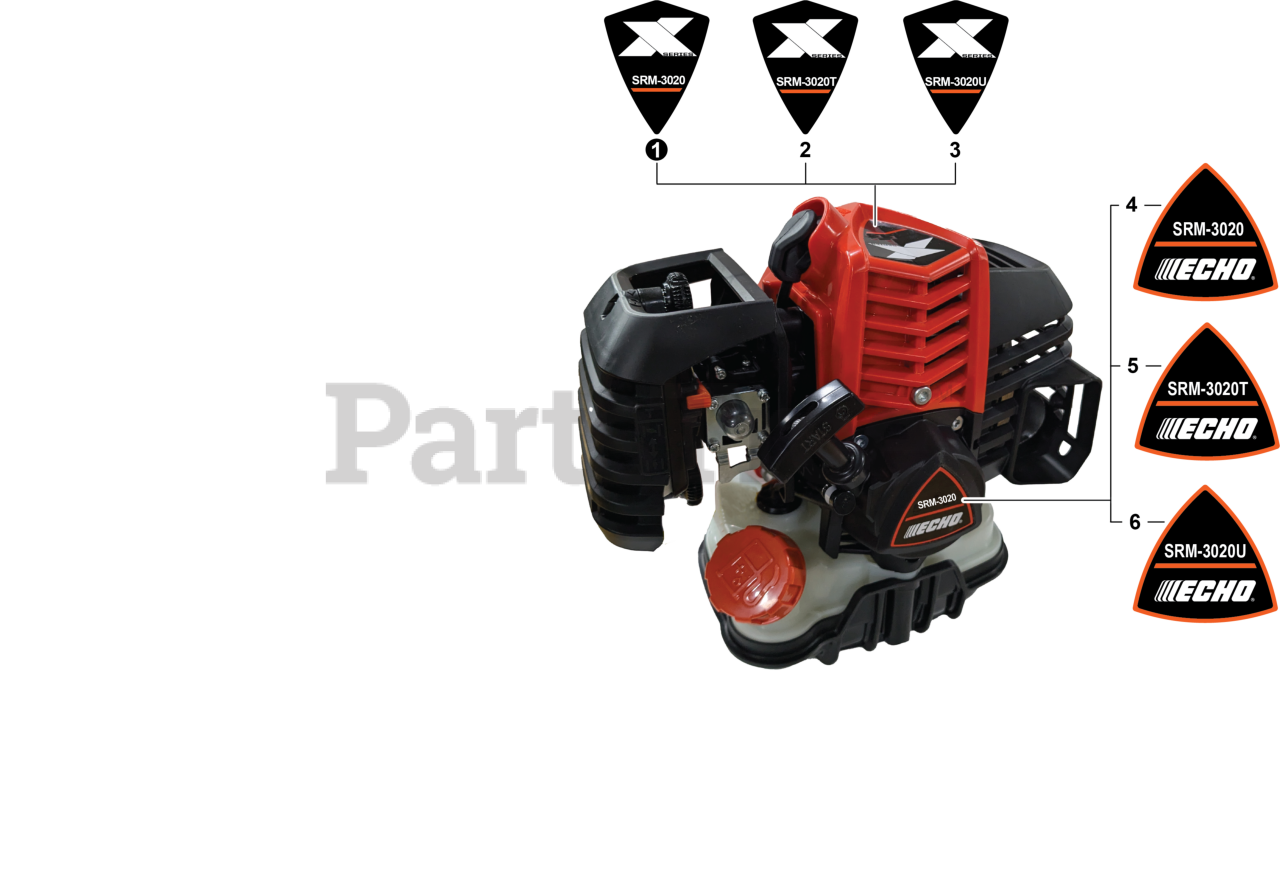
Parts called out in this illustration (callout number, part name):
1	LABEL - MODEL SRM-3020
2	LABEL - MODEL SRM-3020T
3	LABEL - MODEL SRM-3020U
4	LABEL - STARTER - SRM-3020
5	LABEL - STARTER - SRM-3020T
6	LABEL - STARTER - SRM-3020U
